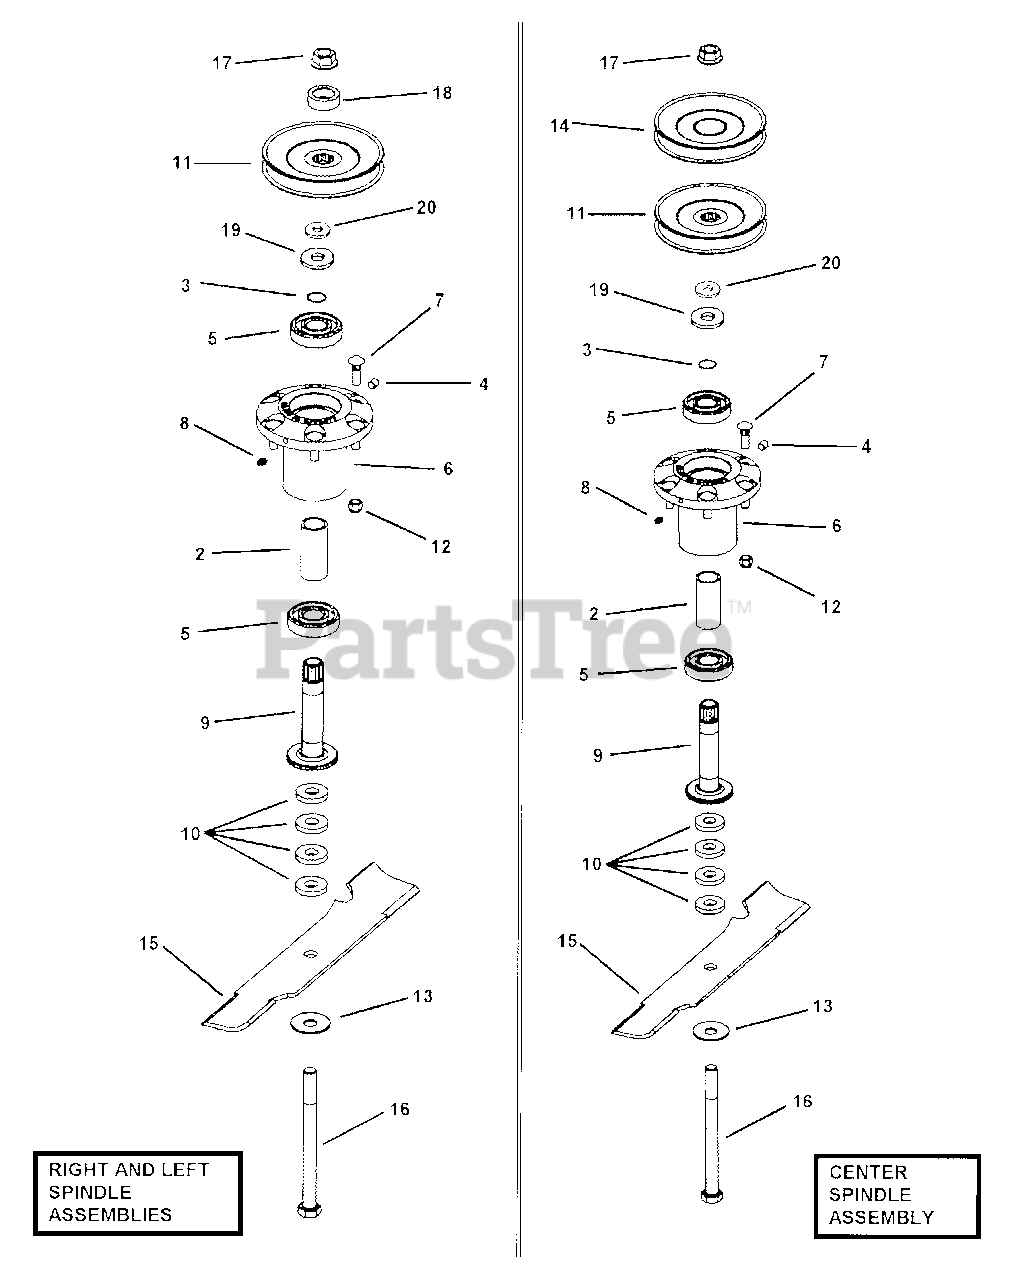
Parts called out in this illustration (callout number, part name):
1	SUB-ASSEMBLY, Spindle (Includes indented items below)
2	SPACER, Bearing
3	RING, Spindle Retaining
4	VENT, Spindle (Alemite # 321839)
5	BALL BEARING (2 per item 1, sub-assembly)
6	HOUSING, Spindle
7	BOLT, Ribbed (3/8-16 x 1-1/4" Thread) (6 per item 1, sub-assembly)
8	FITTING, Lube (1/4-28 Thread; Alemite # 3038-B)
9	SHAFT, Spindle
10	SPACER, Blade
11	PULLEY, 5.75" Diameter
12	NUT, 3/8-16 HEX NYLON LOCK
13	WASHER, Beveled
14	PULLEY, Driven (48" Deck only)
15	BLADE, 16-1/2" (48" Deck only)
16	BOLT, 5/8-11 x 7-1/2" Hex, Grade 5
17	NUT, 5/8-11 Hex Flange Lock, GR5
18	WASHER, Spindle
19	SEAL, Nylos
20	WASHER
